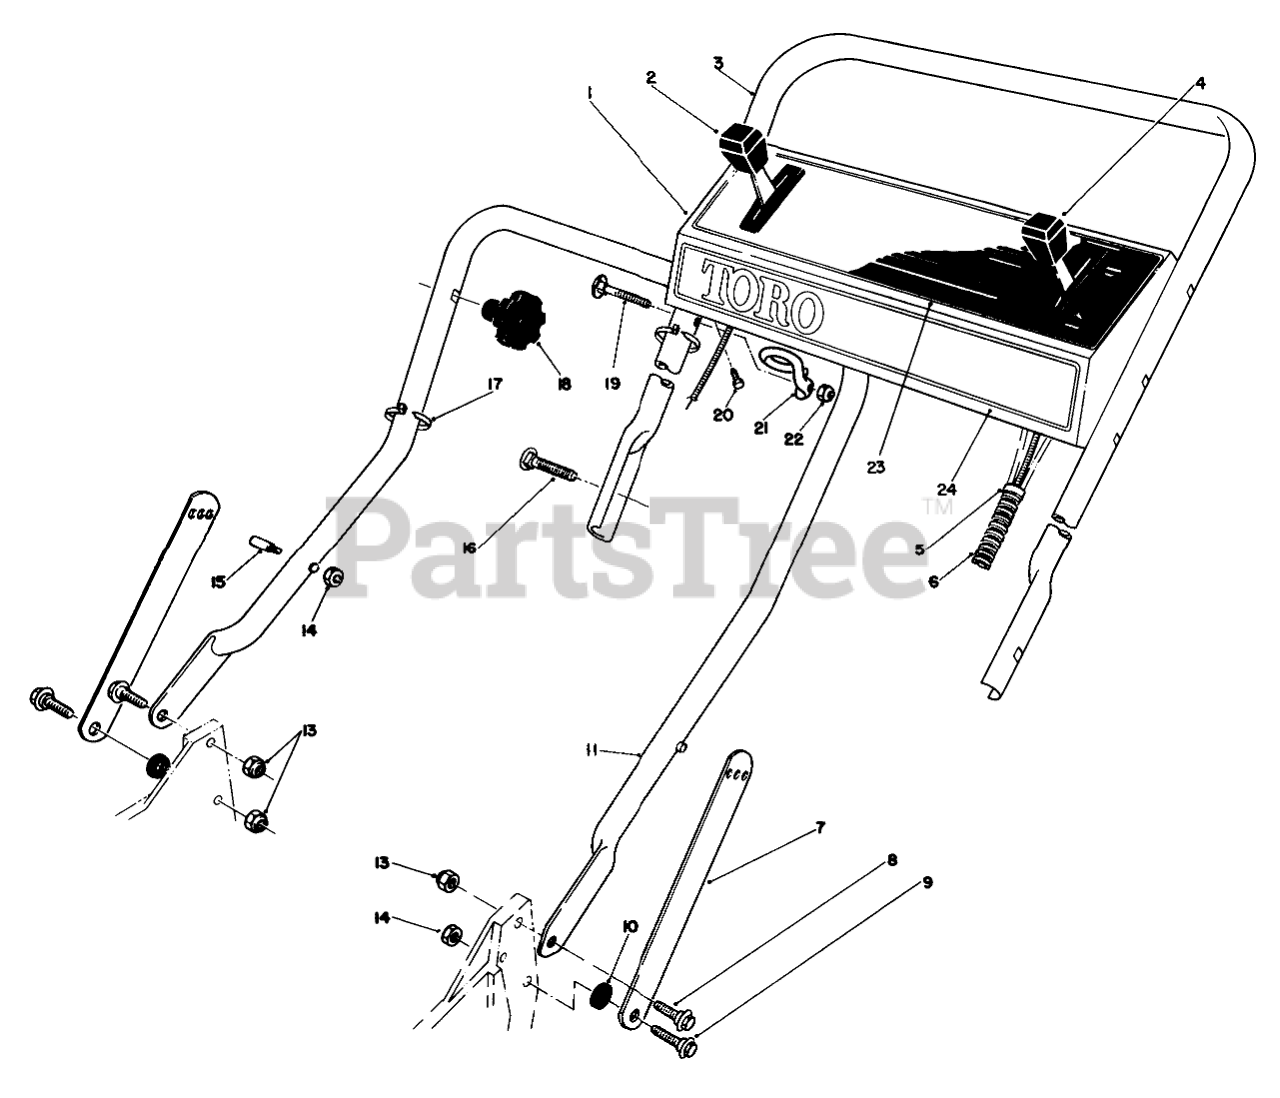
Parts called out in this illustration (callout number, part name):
1	Panel-Control (Incl. Ref. #23)
2	GROUND SPEED CONTROL
3	Handle-Upper
4	THROTTLE CONTROL
5	FITTING-RING
6	CONTROL CABLE COVER
7	Handle Latch
8	SCREW-SHOULDER
9	SCREW-SHOULDER
10	SPACER
11	LOWER HANDLE ASM
13	NUT-LOCK, NI
14	NUT-LOCK, NI
15	HANDLE PIN
16	5/16-18 X 2 HNDLE SCREW
17	TIE-CABLE
19	HANDLE SCREW
20	SCREW-HWHTF
21	Guide
22	NUT-LOCK, NI
23	Decal-Instructions
24	Decal-Toro
